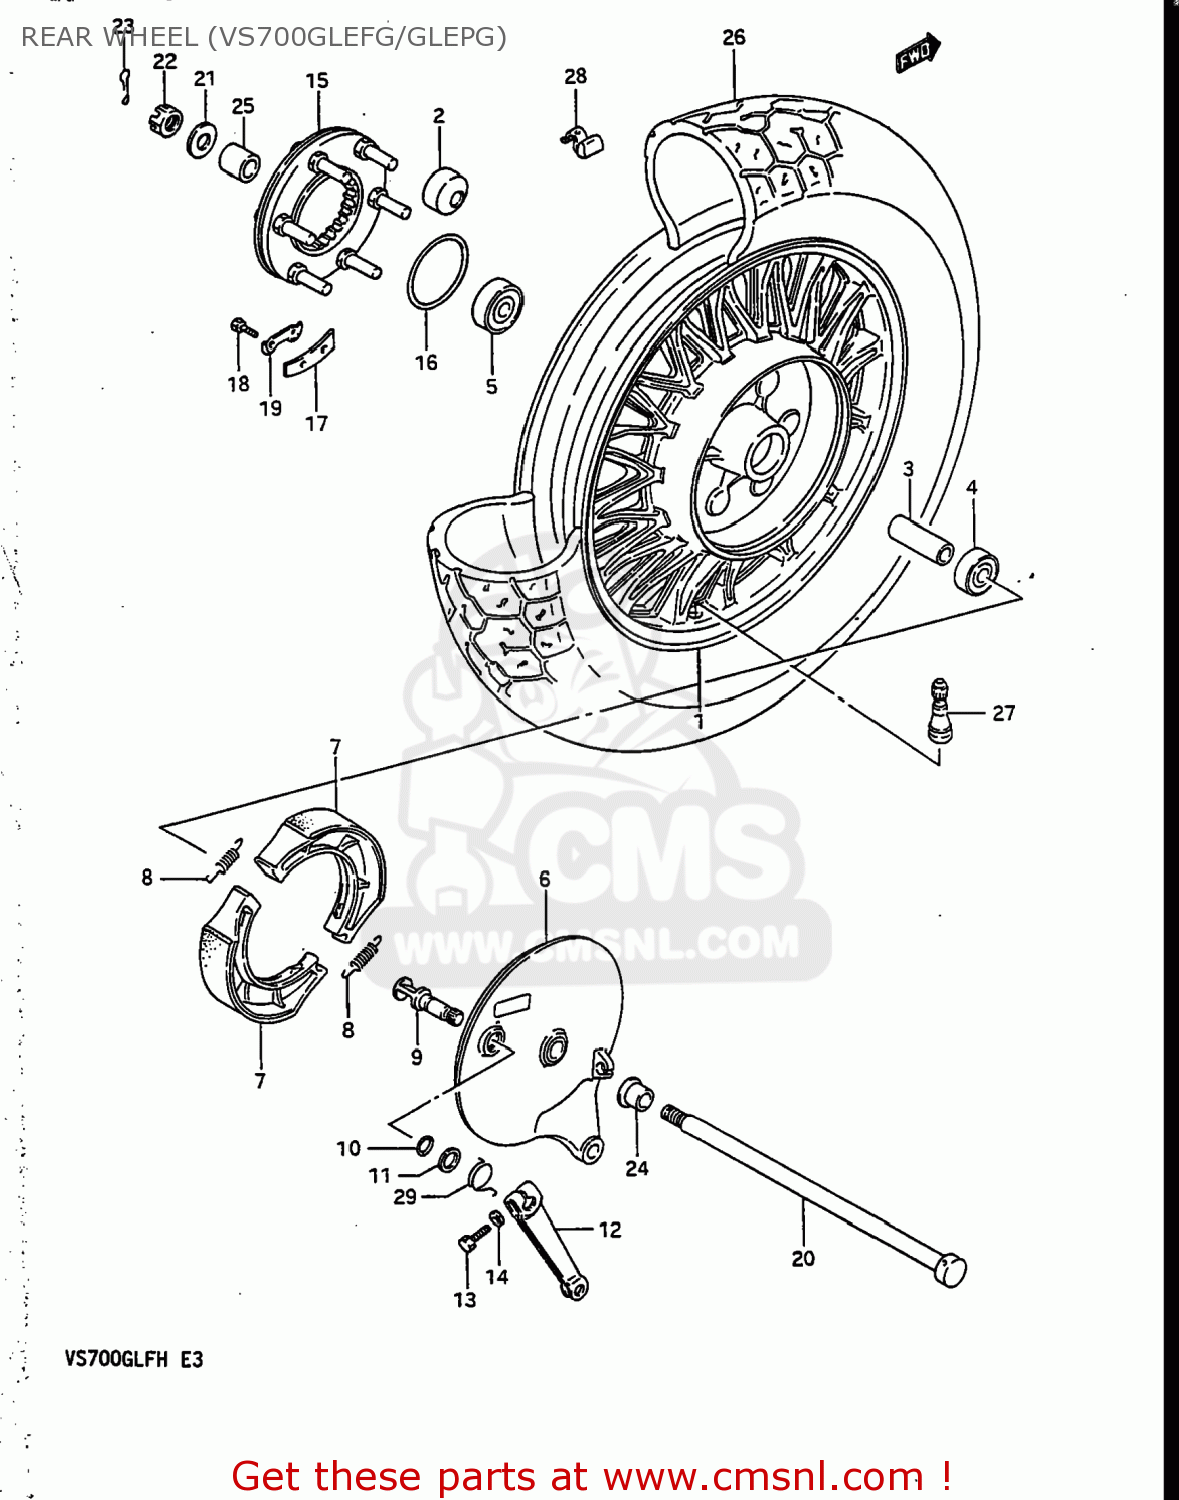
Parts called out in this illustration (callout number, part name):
1	WHEEL SET,REAR
2	BUSHING
3	SPACER,REAR HUB BEARING
4	BEARING
5	BEARING
6	PANEL,REAR BRAKE ANCHOR
7	SHOE SET,BRAKE (MCA)
8	SPRING,BRAKE SHOE
9	CAM,RR BRAKE
10	O-RING,BOSS
11	WASHER (15X24X1.6)
12	LEVER,RR BRAKE CAM
13	BOLT
14	WASHER,LOCK
15	JOINT ASSEMBLY,REAR HUB DRUM
16	O RING(D:2.1,ID:65)
17	WASHER,THRUST(T:1.6)
18	BOLT(6X16)
19	WASHER
20	AXLE,REAR
21	WASHER(16.5X36X3.2)
22	NUT
23	COTTER PIN
24	SPACER,REAR AXLE,RIGHT
25	SPACER,REAR AXLE,LEFT
26	TIRE
27	VALVE ASSEMBLY,WHEEL RIM,P
28	BALANCER,WHEEL
29	SPRING
